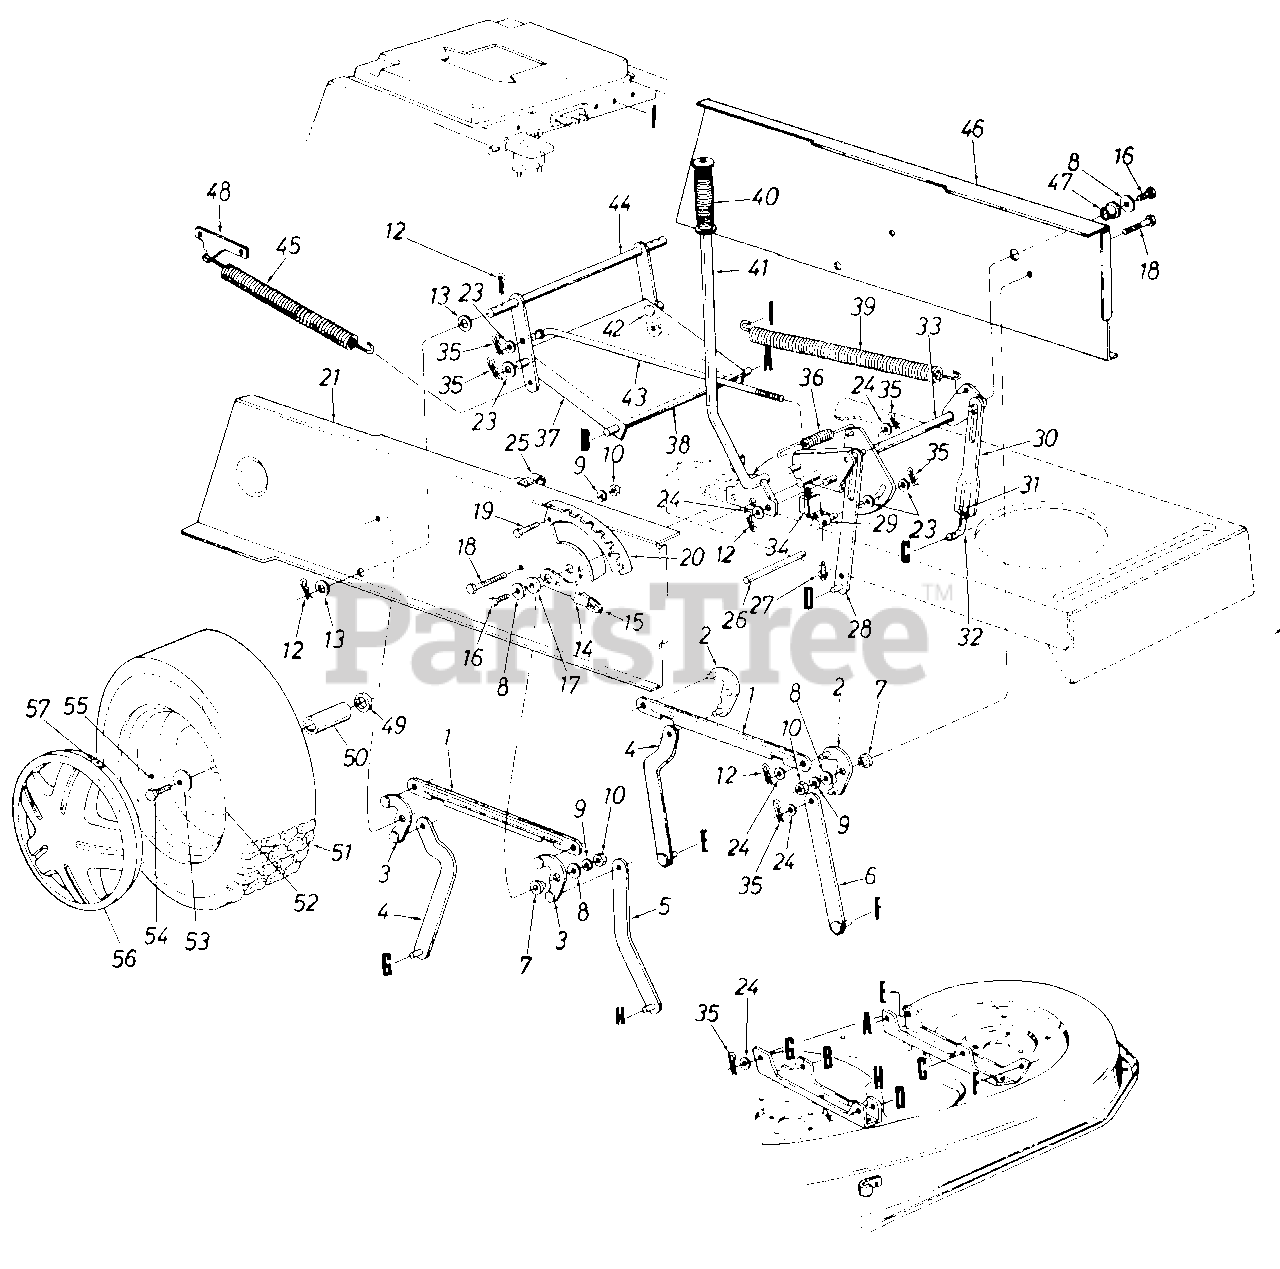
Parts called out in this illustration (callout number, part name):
1	Connecting Rod
2	Pivot Link Ass'y. L.H.
3	Pivot Link Ass'y. R.H.
7	Shld. Spacer .3/8" I.D.
8	Fl-Wash. .344" I.D. x 1.125"
9	L-Wash. 5/16" I.D.
10	Hex Nut 5/16-18 Thd.
12	Cotter Pin 1/8" Dia.
13	Fl-Wash 635" I.D. x 1.0" O.D.
14	Deck Lift Down Stop
15	Knob
16	Hex Wash. TT-Tap Scr. 5/16-18 x .75" Lg.
17	Flange Brg. .63" I.D.
18	Hex Wash. TT-Tap Scr. 5/16-18 x.875" Lg.
19	Hex Bolt 5/16-18 x .75" Lg.
20	Index Brkt.
21	Upper Frame R.H.
23	Fl-Wash. .385" I.D. x .87" O.D.
24	Fl-Wash. .531" I.D. x .93" O.D.
25	Clamp
26	Running Board Rod
27	Truss Mach. Scr. #10 x .5" Lg.
31	Hex Nut 1/2-20 Thd. (Grade 5)
32	Lift Link Adjuster
33	LiH Shaft Ass'y.
34	Safety Switch (Deck)
35	Inter. Cotter Pin 3/8" Dia.
36	Extension Spring
37	Stabilizer Bracket
38	Shaft 1/2" Dia. x 10.28" Lg.
39	Extension Spring
40	Grip
41	Deck Lift Handle Ass'y.
42	Weld Pin .375" Dia. x 1.25" Lg.
43	Disengagement Rod
44	Stabilizer Shaft Ass'y.
45	Extension Spring
46	Upper Frame L.H.
47	Flange Brg. .632" I.D.
48	Deck Spring Brkt.
49	Fl-Wash. .76" I.D. x 1.49" O.D.
50	Sleeve .75" I.D. x 1.0" O.D.
52	Wheel Rim Only
53	Bell-Wash. .345" I.D. x .88" O.D.
54	Hex L-Bolt 5/16-24 x .75" Lg.
55	Air Valve
56	Hub Cap
57	Spring Clip
